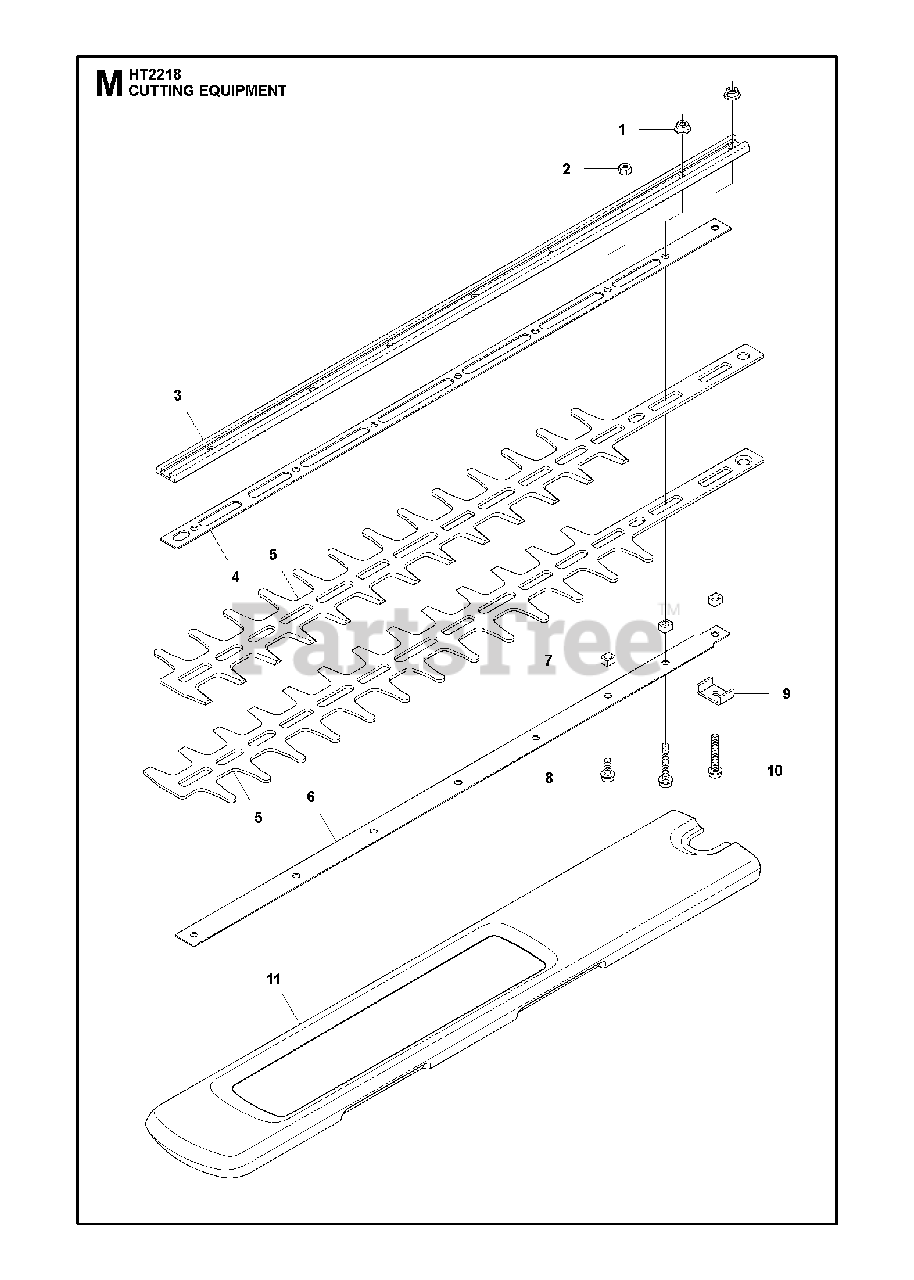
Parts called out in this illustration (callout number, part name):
4	WEAR PLATE
5	BLADE HEDGE TRIMMER
11	TRANSPORT GUARD
